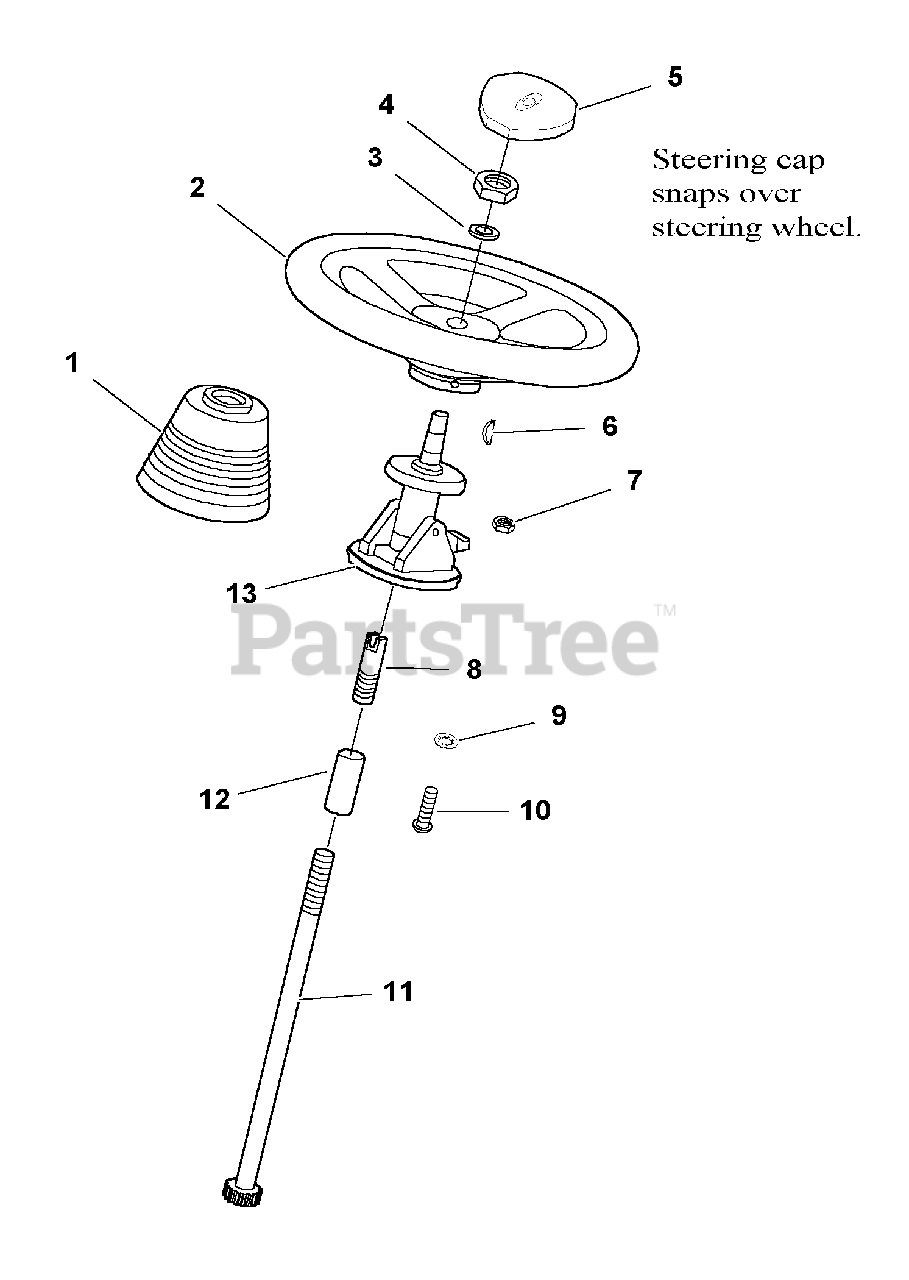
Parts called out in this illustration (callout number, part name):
1	BOOT, Tilt Steering Unit
2	STEERING WHEEL, Tapered Shaft
3	WASHER, 5/8
4	NUT, Hex Lock ESNA, 5/8-11
5	CAP, Steering Wheel, Simplicity
6	KEY, Woodruff
7	NUT, Hex Keps, 1/4-20
8	ADAPTER, Tilt
9	PUSH NUT
10	CARRIAGE BOLT,1/4-20 x 1-1/4
11	SHAFT & PINION ASSEMBLY
13	TILT STEERING ASSEMBLY
